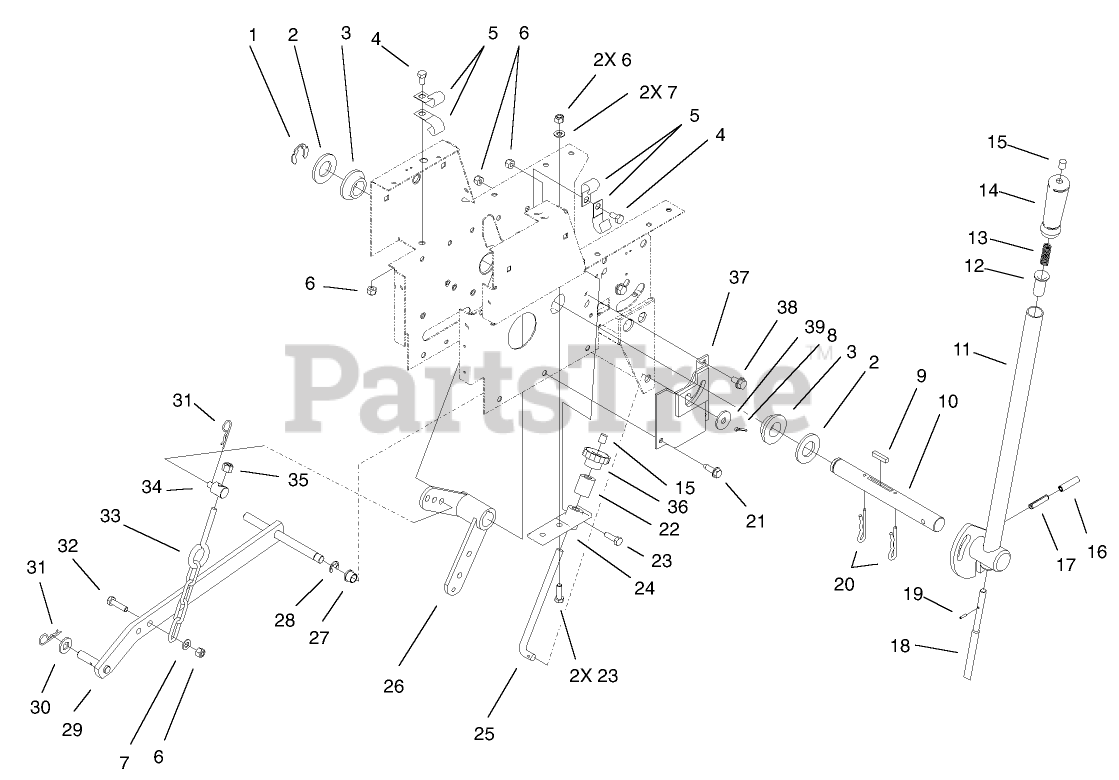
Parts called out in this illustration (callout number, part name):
1	RING-RETAINING
2	WASHER-FLAT
3	BEARING-FLANGE
4	SCREW-HH
5	CLIP
6	NUT-LOCK, NI
7	WASHER-PLAIN
8	PIN-COTTER
9	KEY-SQUARE
10	SHAFT-LIFT LEVER
11	LIFT HANDLE ASM
12	RETAINER-SPRING
13	SPRING-COMPRESSION
14	GRIP-HANDLE
15	CAP-ROD, PLUNGER
16	PIN-SPRING
17	PIN-ROLL
18	ROD-LATCH LIFT
19	PIN-SPIROL
20	PIN-HAIR
21	SCREW-SELF TAP
22	SLEV-LIFT ADJS
23	SCREW-HH
24	CASTING-LIFT LEVER
25	ROD-HEIGHT CONTROL
26	LIFT LEVER ASM
27	BUSHING
28	RING-RETAINING, EXTERNAL
29	LIFT BAR ASM
30	WASHER-FLAT
31	PIN-HAIR
32	SCREW-HH
33	CHAIN-LIFT
34	TRUNNION-LIFT
35	NUT-LOCK, NI
36	KNOB-LIFT CONTROL
37	LIFT LEVER ASM
38	SCREW-HWHTF
39	WASHER-FLAT
